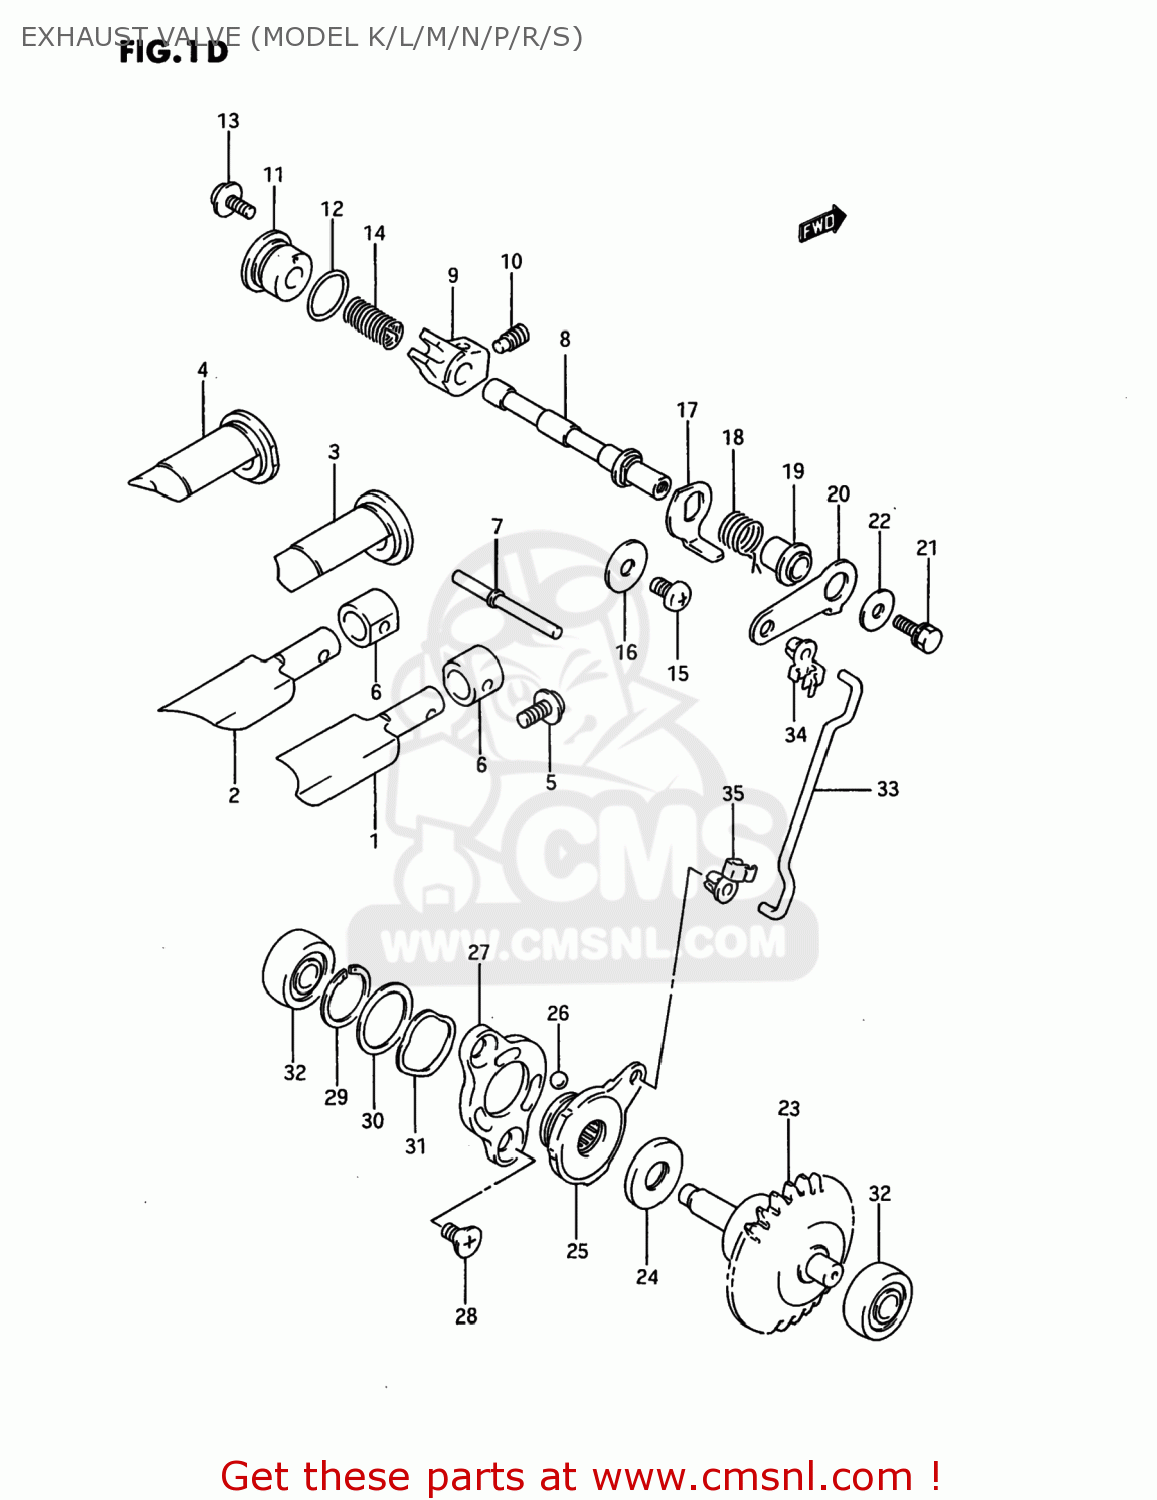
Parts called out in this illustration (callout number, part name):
1	VALVE,EXHAUST,R
2	VALVE,EXHAUST,L
3	GUIDE,EXHAUST VALVE,R
4	GUIDE,EXHAUST VALVE,L
5	SCREW
6	SPACER,EXHAUST VALVE
7	PIN,EXHAUST VALVE 48.5MM
8	SHAFT,EXHAUST VALVE
9	ARM,EXHAUST VALVE SHAFT
10	SCREW(6X10)
11	CAP,EXHAUST VALVE
12	O-RING
13	BOLT
14	SPRING
15	SCREW
16	WASHER
17	LEVER,EXHAUST VALVE NO
18	SPRING
19	SPACER,EXHAUST VALVE
20	LEVER,EXHAUST VALVE NO
21	BOLT
22	WASHER (5.5X16X1.2)
23	GOVERNOR ASSEMBLY,EXHAUST
24	BEARING(10X22X2.8)
25	ACTUATOR,EXHAUST VALVE
26	BALL
27	STARTER,EXHAUST VALVE ACTUATOR
28	SCREW(5X10)
29	CIRCLIP
30	SHIM(19.1X25X0.3)
31	WASHER
32	BEARING(8X22X7)
33	ROD,EXHAUST VALVE
34	BUSH,EXHAUST VALVE ROD NO.1
35	BUSH,EXHAUST VALVE ROD NO.2
